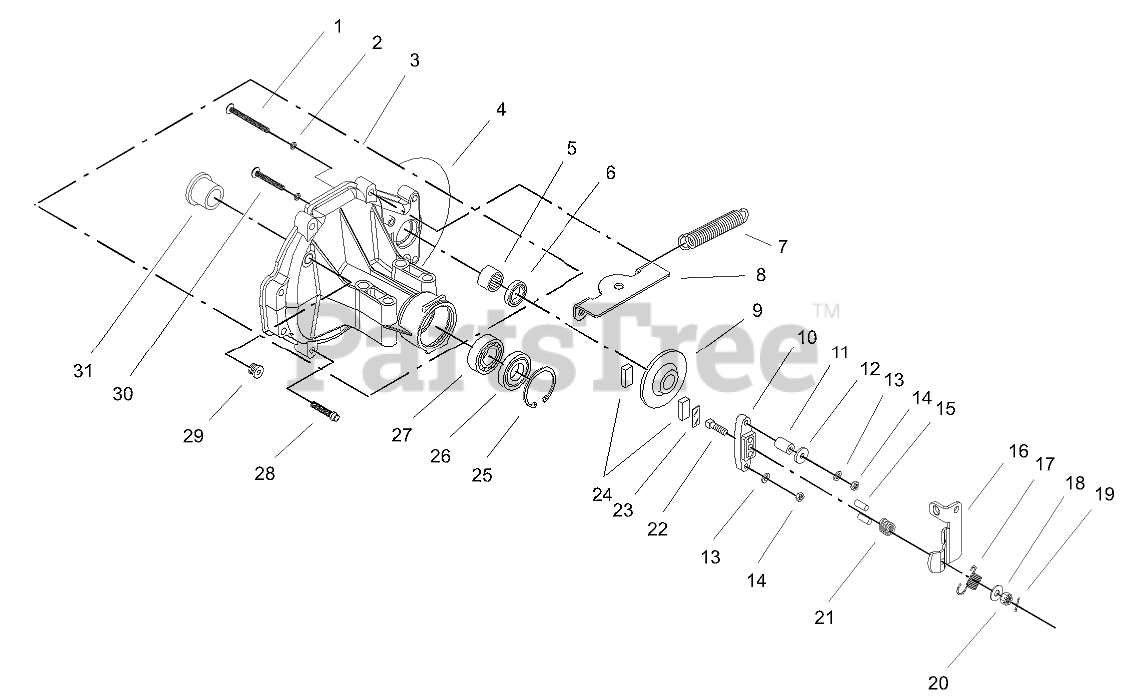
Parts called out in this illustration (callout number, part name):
2	O-RING
3	RH HOUSING ASM
4	SEALANT
5	BEARING-NEEDLE
6	SEAL-LIP
7	SPRING-RETURN
8	BRACKET-CRANK, BELL
9	DISK-BRAKE
10	YOKE-BRAKE
11	SPACER
12	WASHER
13	WASHER-LOCK
15	PIN-BRAKE
16	ARM-BRAKE
17	SPRING-ARM, BRAKE (BIAS)
18	WASHER
19	PIN-COTTER
20	NUT-CASTLE
21	SPRING-BRAKE, ANTI DRAG
22	BOLT-SQH
23	PUCK-PLATE
24	PUCK-BRAKE
25	RING-RETAINING
27	BEARING-BALL
28	SCREW-TTH
29	PLUG-THREAD, STRAIGHT
31	BEARING-FLANGE
